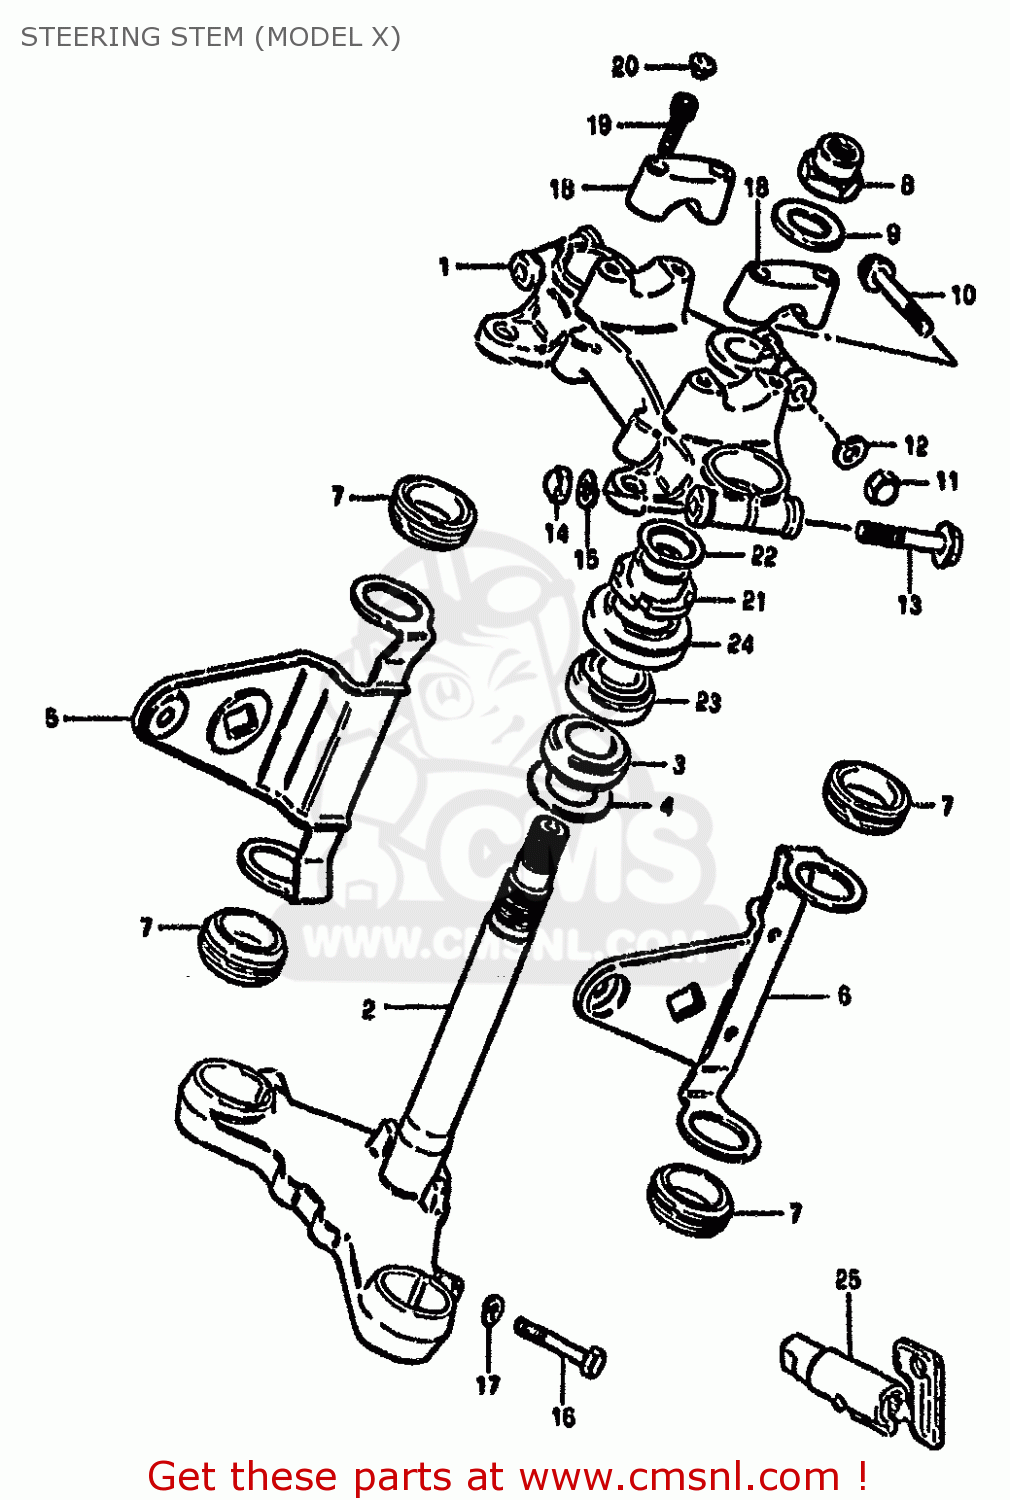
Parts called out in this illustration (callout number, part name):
1	HEAD,STEERING STEM
2	STEM,STEERING
3	BEARING
4	WASHER,THRUST
5	BRACKET,HEADLAMP,RIGHT
6	BRACKET,HEADLAMP,LEFT
7	CUSHION,HEADLAMP BRACKET
8	NUT,STEERING STEM
9	WASHER,STEM HEAD
10	BOLT
11	NUT,M8X1.25X12
12	LOCK WASHER
13	BOLT 10X55
14	NUT
15	LOCK WASHER
16	BOLT 10X40
17	LOCK WASHER
18	HOLDER,HANDLEBAR(BLACK)
19	BOLT
20	CAP(OD:14.5)
21	NUT,STEERING STEM
22	WASHER(18.5X24X1)
23	TAPER,ROLLER BEARING
24	DUST SEAL,STEERING,UPPER
25	LOCK ASSEMBLY,STEERING (NEI
